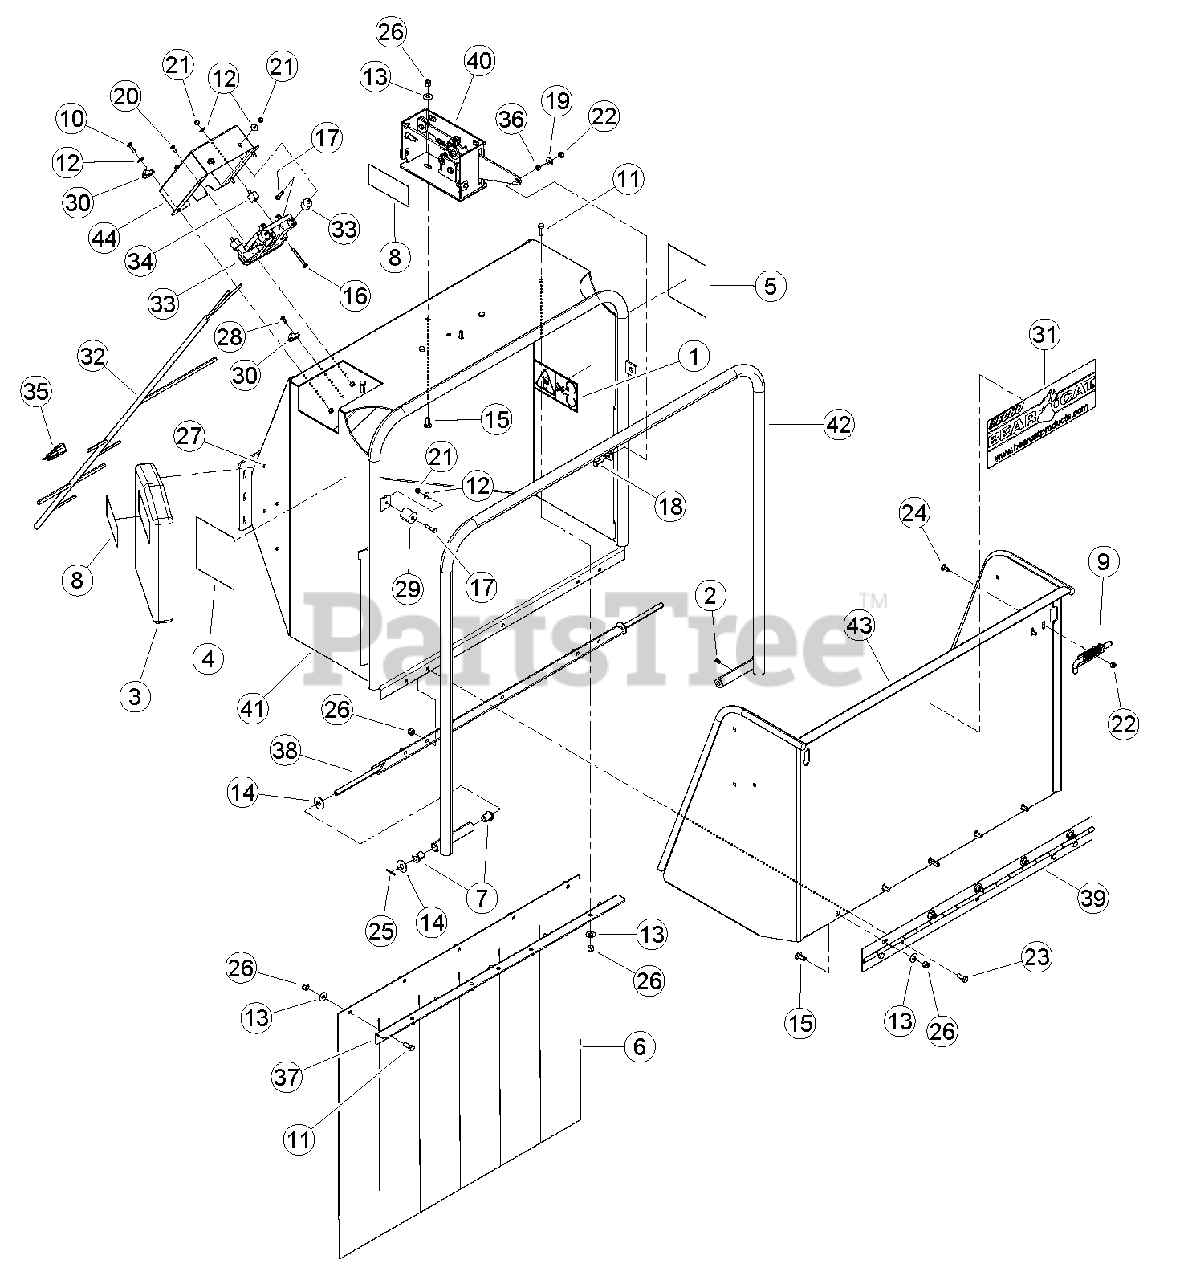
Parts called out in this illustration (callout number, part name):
1	DECAL, BLADE DANGER ISO
2	FITTING, 1/4 SELF-TAP GREASE
3	CONTAINER, INSTR. MANUAL
4	DECAL, FEED POSITION
5	DECAL, FEED POSITION
6	FLAP, CHUTE
7	BUSHING, 1/2 X 1 FLANGE LUBE
8	DECAL, MUTILINGUAL MANUAL
9	LATCH, RH HINGE
10	BOLT, 1/4 X 1 HEX HD GR5 ZP
11	BOLT, 3/8 X 1 HEX HD GR5 ZP
12	WASHER, 1/4 FLAT ZP
13	WASHER, 3/8 FLAT ZP
14	WASHER, 1/2 FLAT ZP
15	BOLT, 3/8 X 1 CRG GR5 NC ZP
16	BOLT, 1/4 X 2-1/4 HEX HD GR5 ZP
17	BOLT, 1/4 X 1-1/4 HEX HD GR5 ZP
18	BOLT, 5/16 X 1 HEX HD GR5 NC ZP
19	WASHER, 5/16 FLAT ZP
20	BOLT, 1/4 X 5/8 HEX HD GR5 ZP
21	NUT, 1/4 NE NYLOCK ZP
22	NUT, 5/16 NE NYLOCK ZP
23	BOLT, 3/8 X 1-1/4 HEX HD GR5 ZP
24	BOLT, 5/16 X 3/4 CRG GR5 NC ZP
25	PIN, 1/8 X 1.00 COTTER ZP
26	NUT, 3/8 NE NYLOCK ZP
27	RIVET, AL BLIND 1/4 X 1/2 DOME HEAD
28	RIVET, AL BLIND 1/4 X 3/4 DOME HEAD
29	BUMPER, RECESSED RUBBER
30	CLAMP, CABLE MOUNT
31	DECAL, BEARCAT WEB
32	HARNESS, 6" DIESEL PLUS 1 CONTROLLER
33	CONTROLLER, PLUS 1 CHIPPER
34	BUMPER, 1" OD W/1/4" STUD
35	PLUG, JUMPER HARNESS
36	SPACER, IDLER PIVOT
37	SUPPORT, CHIPPER FLAP
38	WELDMENT, CONTROL PIVOT
39	HINGE, EXTENSION TRAY
40	ASSEMBLY, SWITCH BOX
41	WELDMENT, CHIPPER CHUTE
42	WELDMENT, CONTROL ARM
43	WELDMENT, EXTENSION TRAY
44	ENCLOSURE, PLUS 1 MOUNT
